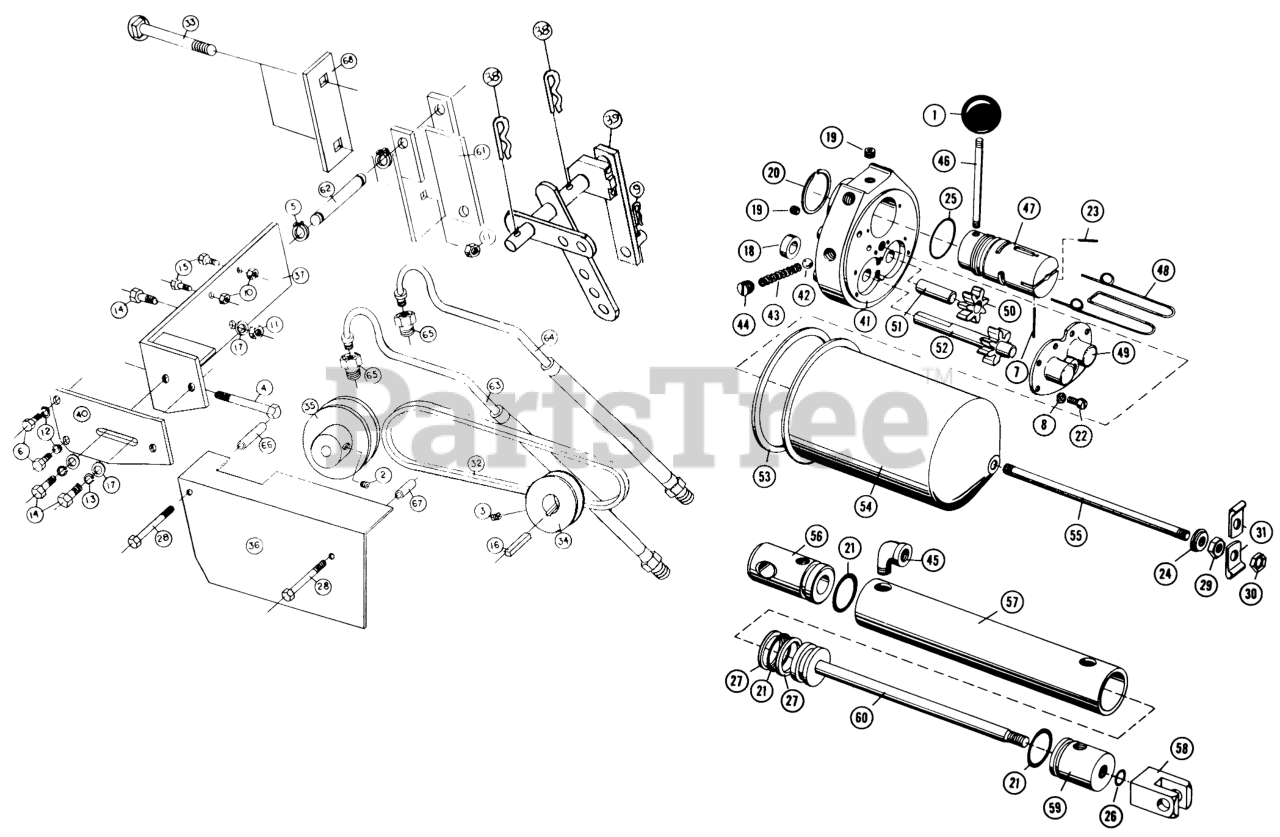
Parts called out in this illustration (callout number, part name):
1	Knob
2	Set Screw 5/16-18 x 5/16
3	Set Screw 1/4-20
4	Bolt 3/8-16 x 2 3/4
5	Snap Ring 3/4 I.D.
6	Bolt Hex 5/16-18
7	SPIROL PIN
8	Lockwasher
9	Hairpin
10	Nut-Nylok
12	Lockwasher
13	Lockwasher
14	Bolt 3/8-16 x 3/4
15	Bolt-1/4-20 x 5/8
16	Key 1/4 x 1/4 x 1
17	Washer
18	Seal
19	Allen Hd. Pipe Plug 1/8
20	Snap Ring
21	O Ring
22	Cover Screw #10-32 x 7/16
23	Roll Pin 5/12 x 7/8
24	Washer
25	O Ring
26	O Ring
27	Back Up Washer
28	Bolt-Hex 5/16-18 x 2 3/4
29	3/8-16 Jam Nut
30	Hex Pal Nut 3/8-16
31	Tube Clamp 1/4 I.D.
32	"V" Belt 3L-510
33	Bolt-Carriage 3/8-16 x 3
34	Pulley 2 1/4 Dia.
35	Pulley
36	Belt Guard
37	Pump Mounting Bracket
38	Hairpin
39	Ass-y. Lift Lever Hyd.
40	Spacer
41	60-950-01 GIL 6HP 2
42	Ball
43	Spring
44	Plug
45	Street Elbow 1/4 NPTF
46	Handle
47	Spool Valve
48	Spring
49	Cover
50	Gear
51	Shaft
52	Drive Shaft Ass-y.
53	Gasket
54	Reservoir
55	Stud
56	Head
57	Tube
58	Clevis
59	Guide
60	Piston Rod Ass-y.
61	Cylinder Support
62	Pin
63	Hose
64	Hose
65	Tube Coupling
66	Pipe Spacer 1/4 x 2 1/8 lg
67	Washer-Seal
68	Link-Mtg. Bracket
